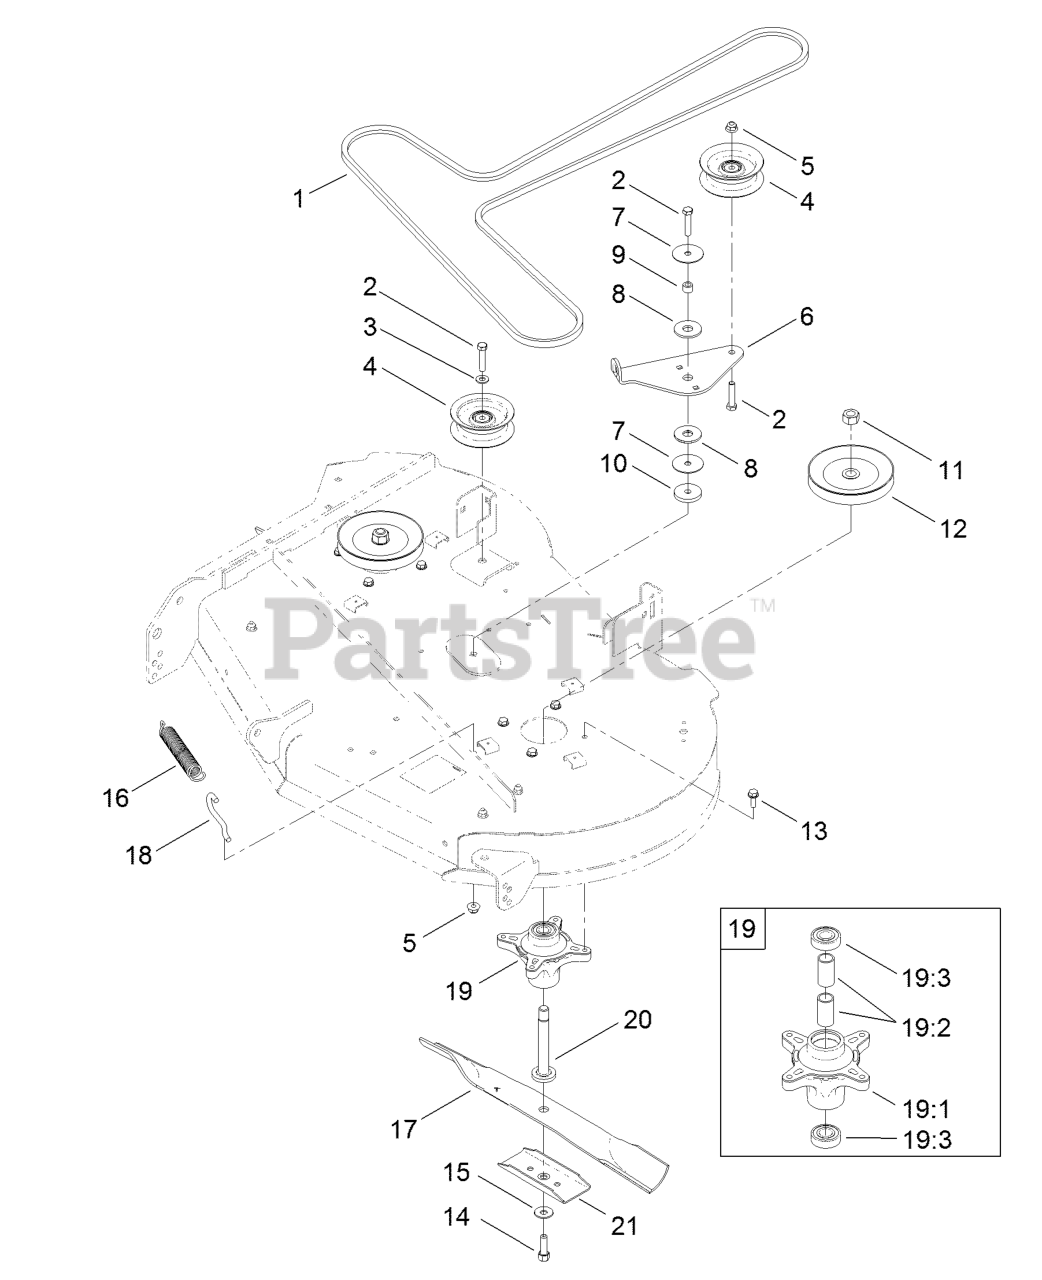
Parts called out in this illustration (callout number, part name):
1	V-BELT
2	SCREW-HH
3	WASHER-FLAT
5	NUT-HF, NI
6	ARM-IDLER
8	WASHER-FRICTION, COMPOSIT
10	WASHER-PLAIN
11	NUT-HEX
12	PULLEY
13	SCREW-TAPTITE
14	SCREW-HH
15	WASHER-BELLEVILLE
16	SPRING-EXTENSION
17	BLADE-21.6 INCH
18	HOOK-RETURN, SPRING
19	SPINDLE ASM
20	SHAFT-SPINDLE
21	STIFFENER-BLADE
